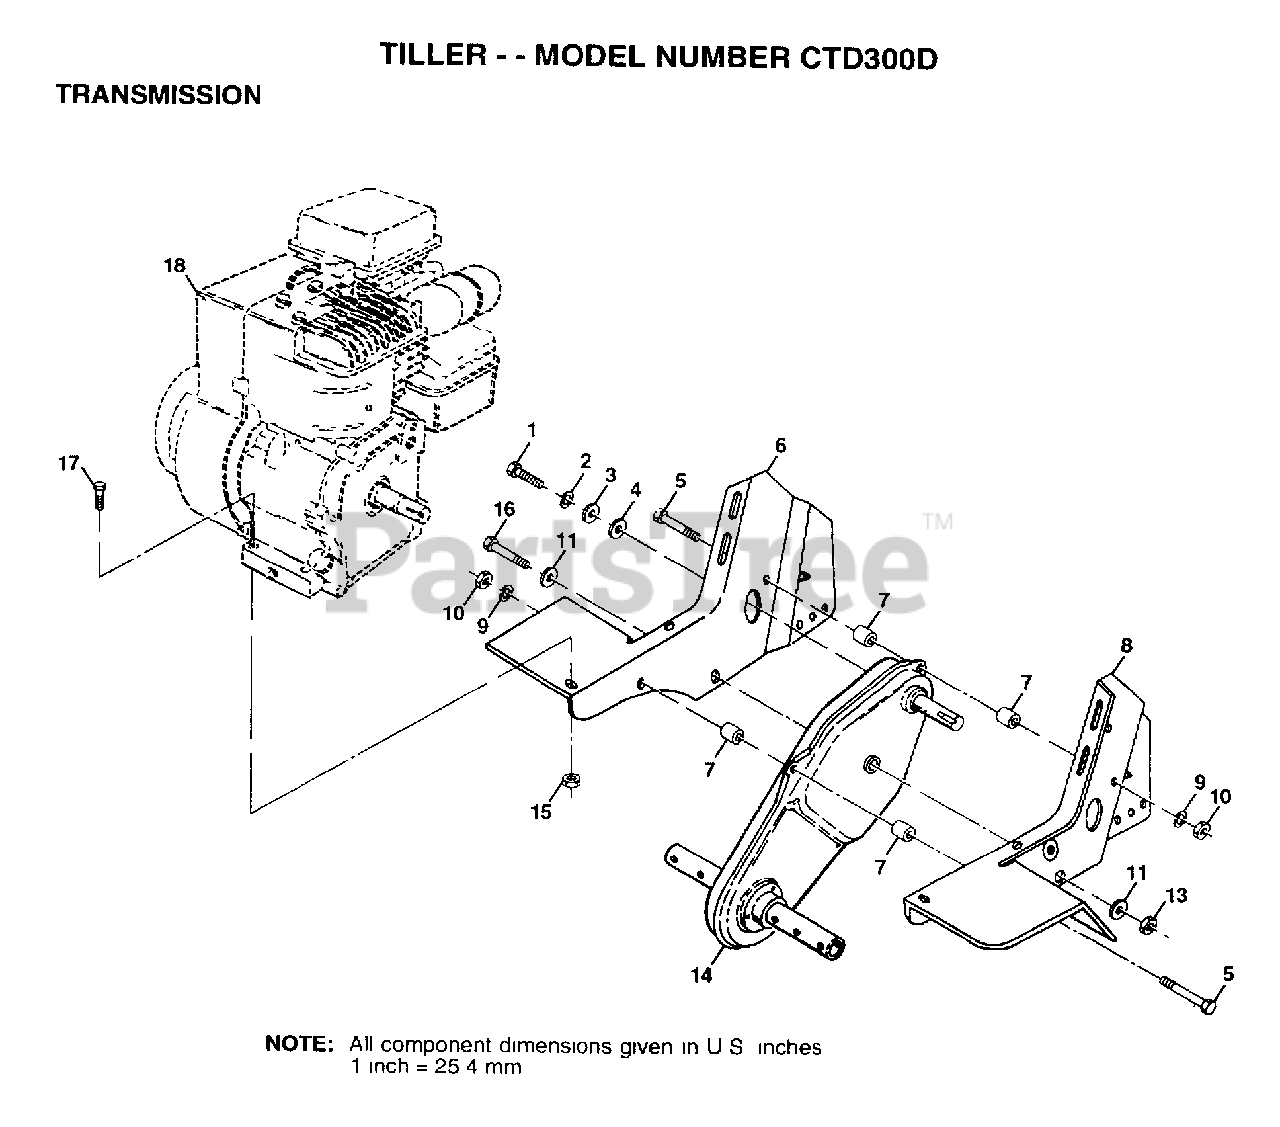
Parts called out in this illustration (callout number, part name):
1	BOLT
2	LOCKWASHER
3	WASHER
4	WASHER
6	BRACKET.ENGINE.RH
7	SPLIT SPACER RT
8	BRACKET.ENGINE.LH
9	LOCKWASHER
10	NUT.HEX.5/16-18
11	WASHER
13	NUT
16	BOLT HEX 3/8-16
17	BOLT.HEX.5/16-1.5
